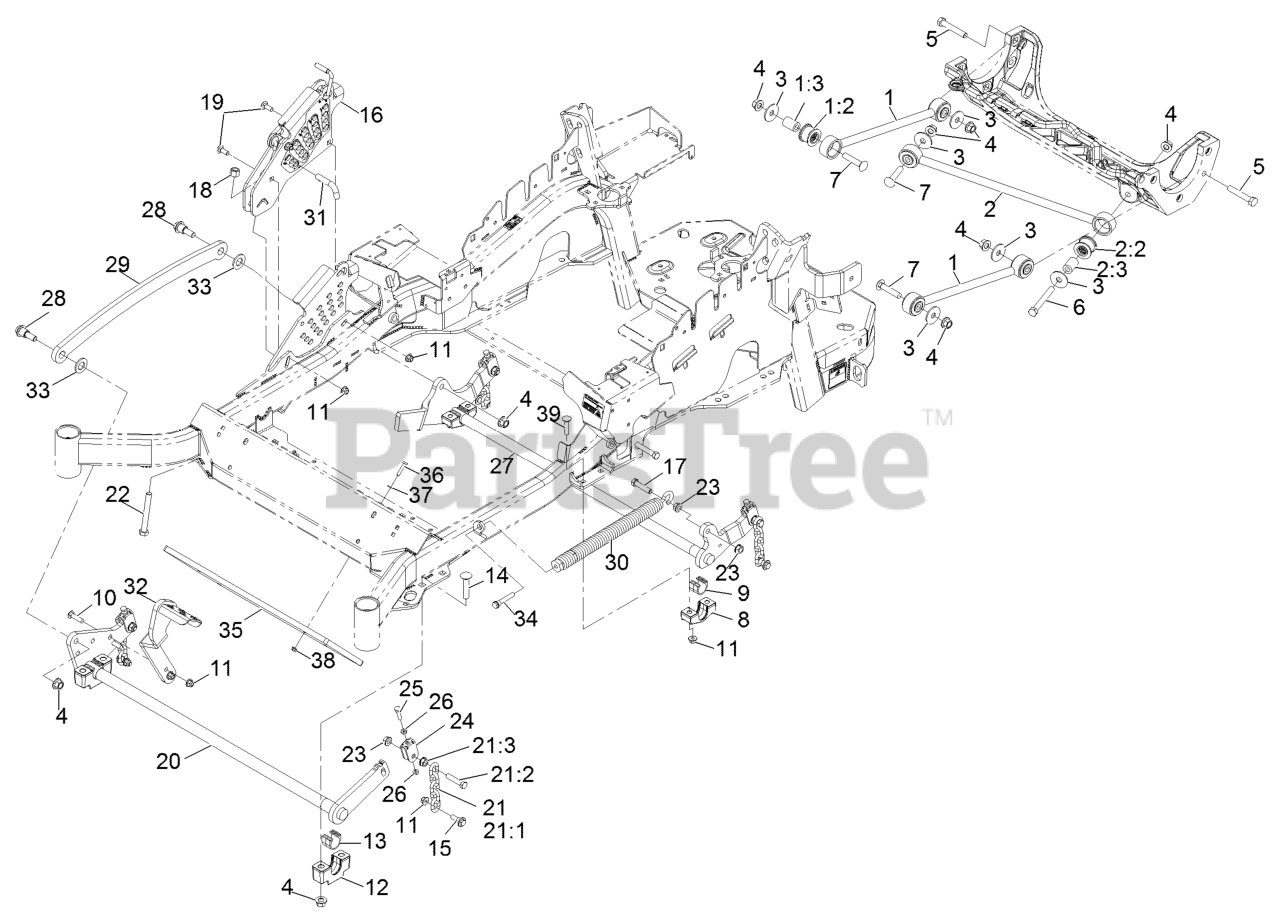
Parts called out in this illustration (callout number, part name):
1	DECK STRUT ASM
1:2	BUSHING-SUSPENSION, RUBBER
2	PANHARD ROD ASM
2:2	BUSHING-SUSPENSION, RUBBER
3	WASHER-THRUST
4	Nut-Lock 1/2-13
5	SCREW-HH
6	SCREW-HH
7	SCREW-CARR
9	BEARING-CROSS SHAFT, REAR
10	SCREW-CARR
11	NUT-HF, NI
12	SUPPORT-CROSS SHAFT, BEARING
13	BEARING-CROSS SHAFT, FRON
14	Bolt-Carriage 1/2-13 X 2 1/2 Spl Neck
15	SCREW-SHOULDER, HHF
16	HOC ASM
17	SCREW-HH
18	NUT-LOCK, NI
19	BOLT-CARR
21	DECK LIFT CHAIN ASM
21:1	CHAIN-LIFT, DECK
21:2	SCREW-HH
22	BOLT-TAP
24	YOKE-ADJUST, DECK
25	SCREW-HH
26	NUT-JAM
27	LIFT-DECK, REAR
28	SCREW-SHOULDER, HHF 1/2-13 X 1.12
29	LINK-LIFT, DECK
30	SPRING-EXTENSION
31	PIN-HOC
32	LEVER-FOOT
33	WASHER-FLAT
34	BOLT-SHOULDER
35	WEIGHT,TOE BOARD
36	SCREW-HH
37	WASHER-FLAT
39	SCREW-CARR
